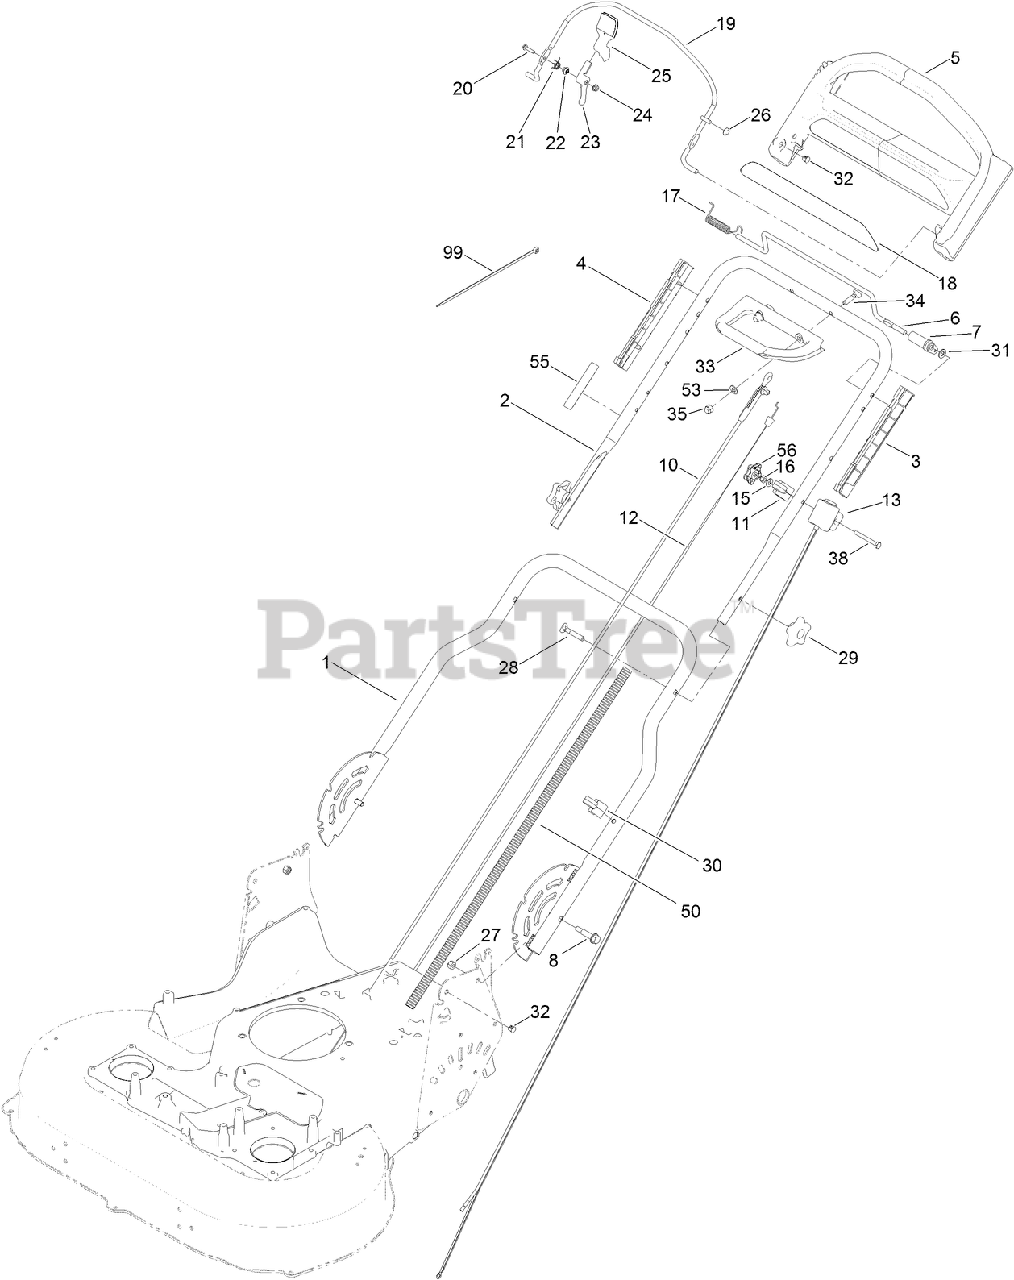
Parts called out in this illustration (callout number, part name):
1	HANDLE-LOWER
2	HANDLE-UPPER
3	GUIDE-LH
4	GUIDE-RH
5	HANDLE-CONTROL
7	LEVER-TRACTION
8	BOLT-SHOULDER, HHF
12	CABLE-TRACTION
13	SWITCH HOUSING ASM
15	WASHER-FLAT
16	NUT-LOCK, NI
18	DECAL-HANDLE
19	BAIL-BRAKE
20	SCREW-HWH
21	SPRING-TORSION
22	SPACER
23	LEVER
24	NUT-LOCK, FLANGE
26	NUT-SPEED
27	NUT-LOCK, NI
28	SCREW-HANDLE
29	KNOB-HANDLE
30	GUIDE-CABLE
31	SPACER
32	PLUG-DOME
33	HANDLE-ASSIST, TRACTION
34	SCREW-HANDLE, LOCK
35	NUT-ACORN
38	SCREW-HH
50	CONDUIT-CONVOLUTED
53	WASHER-PLAIN
56	KNOB-HANDLE, LOCKING
99	TIE-CABLE
